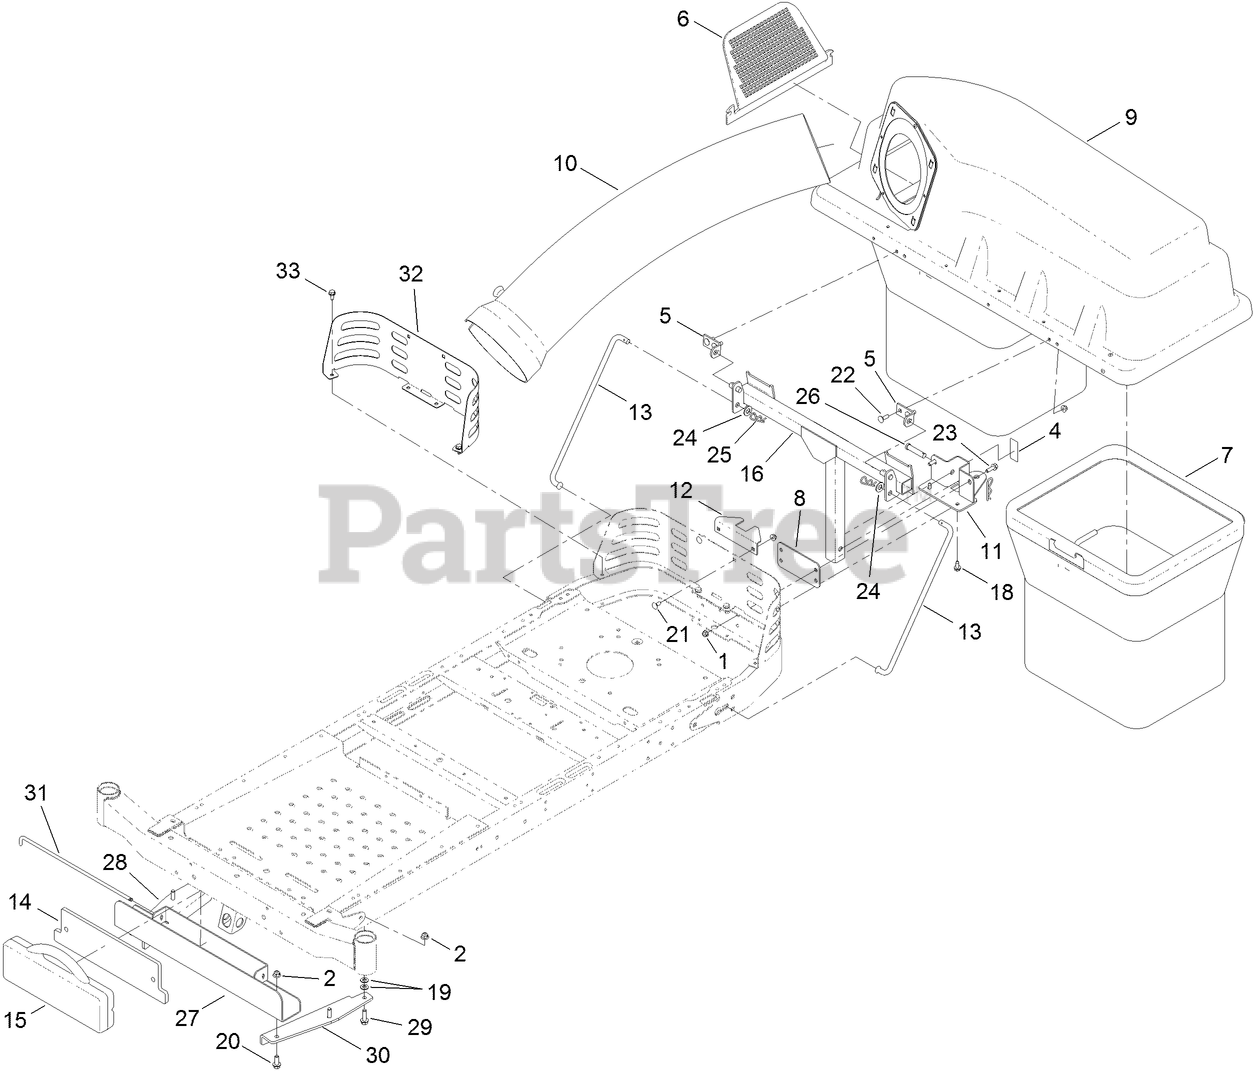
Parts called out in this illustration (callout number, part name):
1	NUT-HF, NI
2	NUT-HF, NI
5	BRACKET-PIVOT, HOPPER
6	SCREEN-BAGGER
7	BAG ASM
9	BAGGER TOP ASM
10	TUBE-BAGGER
11	SUPPORT-BAGGER
12	BRACKET-STABILIZER
13	ROD-SUPPORT
16	FRAME-PIVOT
18	SCREW-HWHTF
19	WASHER-FLAT
20	SCREW-HHF
21	BOLT-CARR
22	BOLT-CARR
23	SCREW-HHF
24	WASHER-FLAT
25	PIN-HAIR
26	PIN-CLEVIS
27	CHANNEL-WEIGHT, BAGGER
28	BRACKET-BAGGER WEIGHT, RH
29	SCREW-HHF
30	BRACKET-BAGGER WEIGHT, LH
31	PIN-WEIGHT
32	GUARD-REAR
33	SCREW-HWHTF
